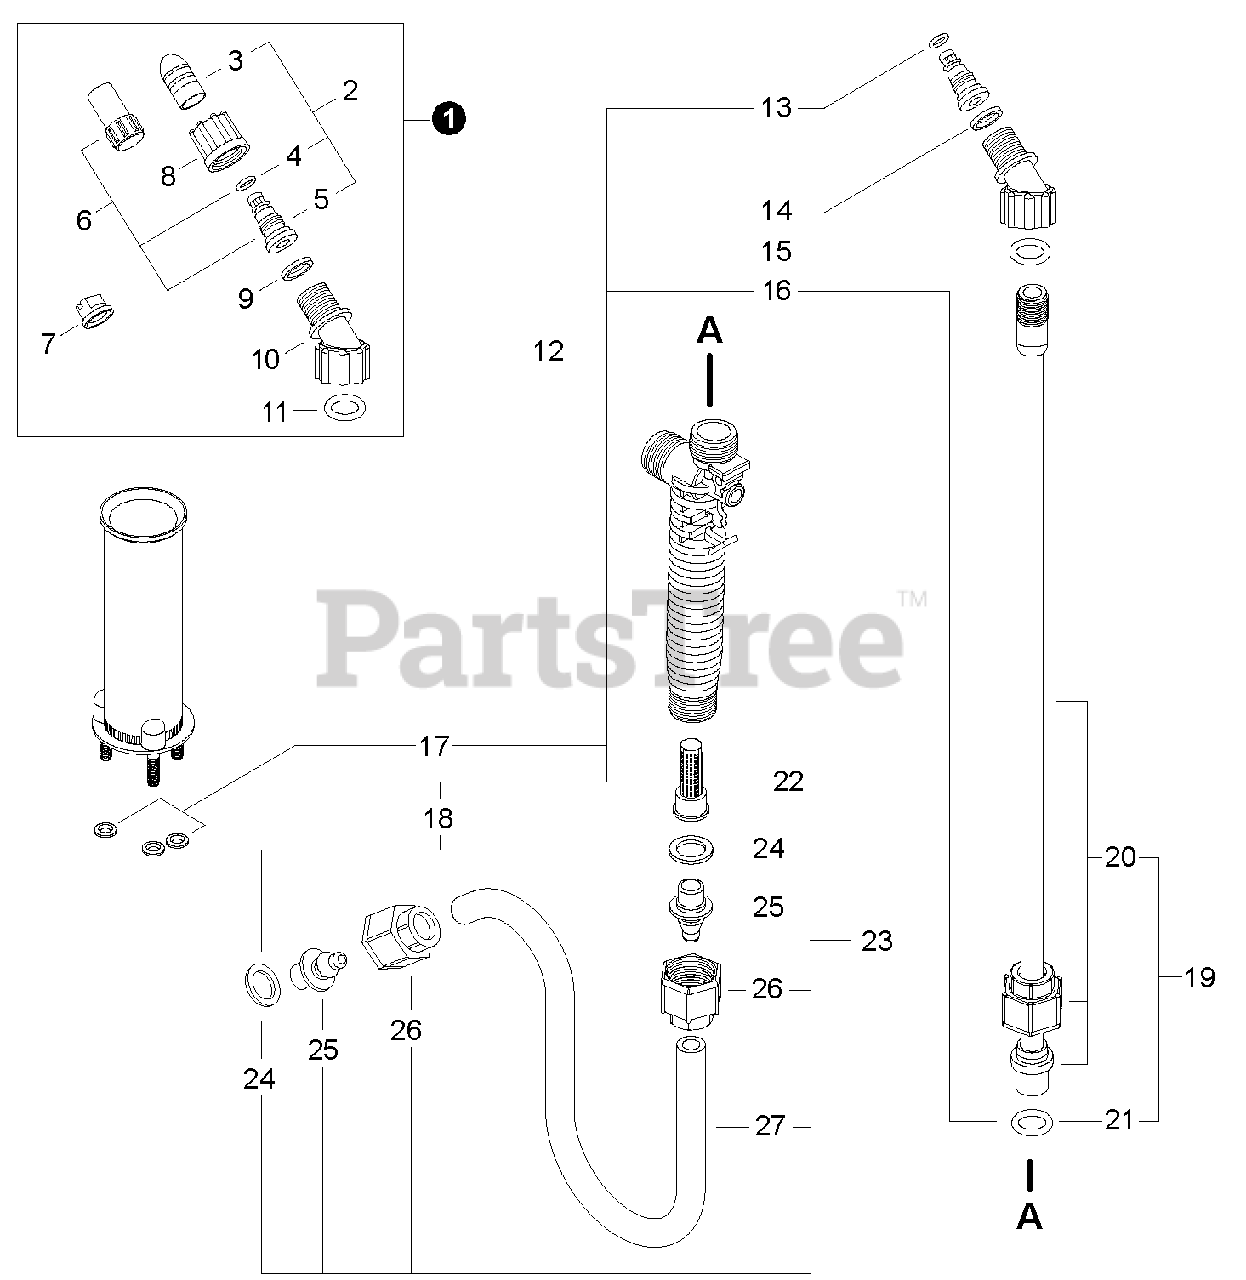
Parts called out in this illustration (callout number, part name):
1	NOZZLE KIT
2	NOZZLE KIT - BRASS
3	CAP, NOZZLE - BRASS
4	O-RING
5	BODY, NOZZLE
6	NOZZLE KIT - PLASTIC
7	NOZZLE - FLAT FAN
8	NUT, NOZZLE
9	GASKET, NOZZLE
10	ELBOW, NOZZLE
11	O-RING
12	GASKET KIT, BPE
13	O-RING
14	GASKET
15	O-RING
16	O-RING
17	GASKET, STUD
18	GASKET, ADAPTER
19	SPRAY WAND ASSY
20	WAND, SPRAYER
21	O-RING
22	FILTER, SPRAY GUN
23	HOSE ASSY
24	GASKET, ADAPTER
25	ADAPTER, HOSE - BLACK
26	NUT, HOSE
27	HOSE - 1210mm -- BLACK
